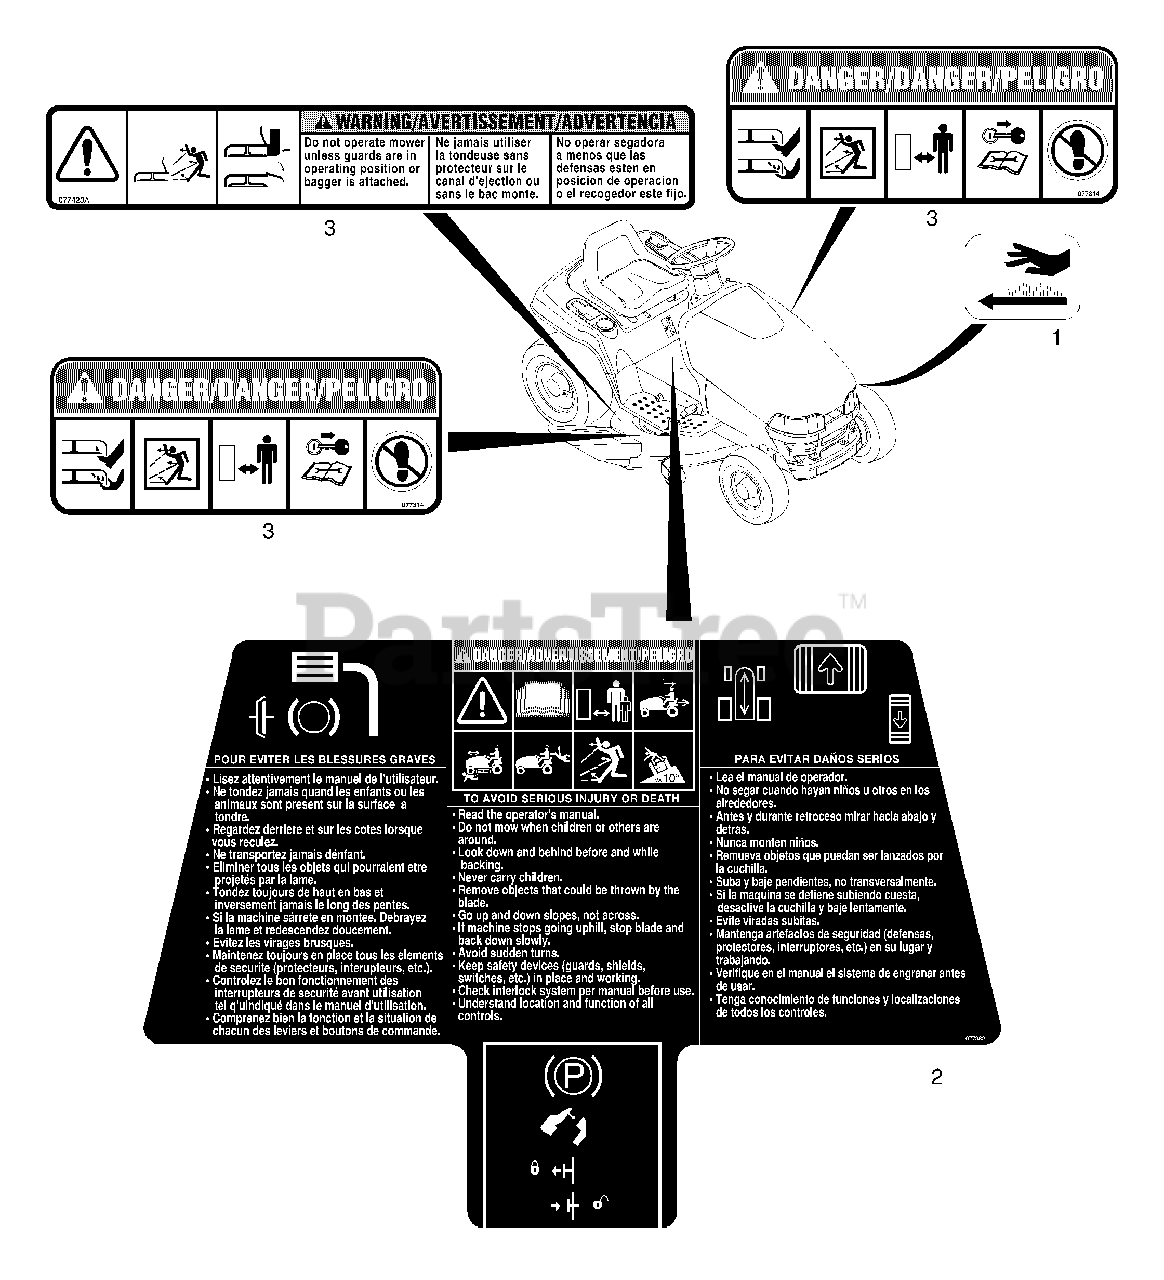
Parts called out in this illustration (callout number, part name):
1	DECAL- HOT SURFACE SYMB.
2	DECAL OPERATING INSTRUCTIONS
3	DECAL SET - DECK
